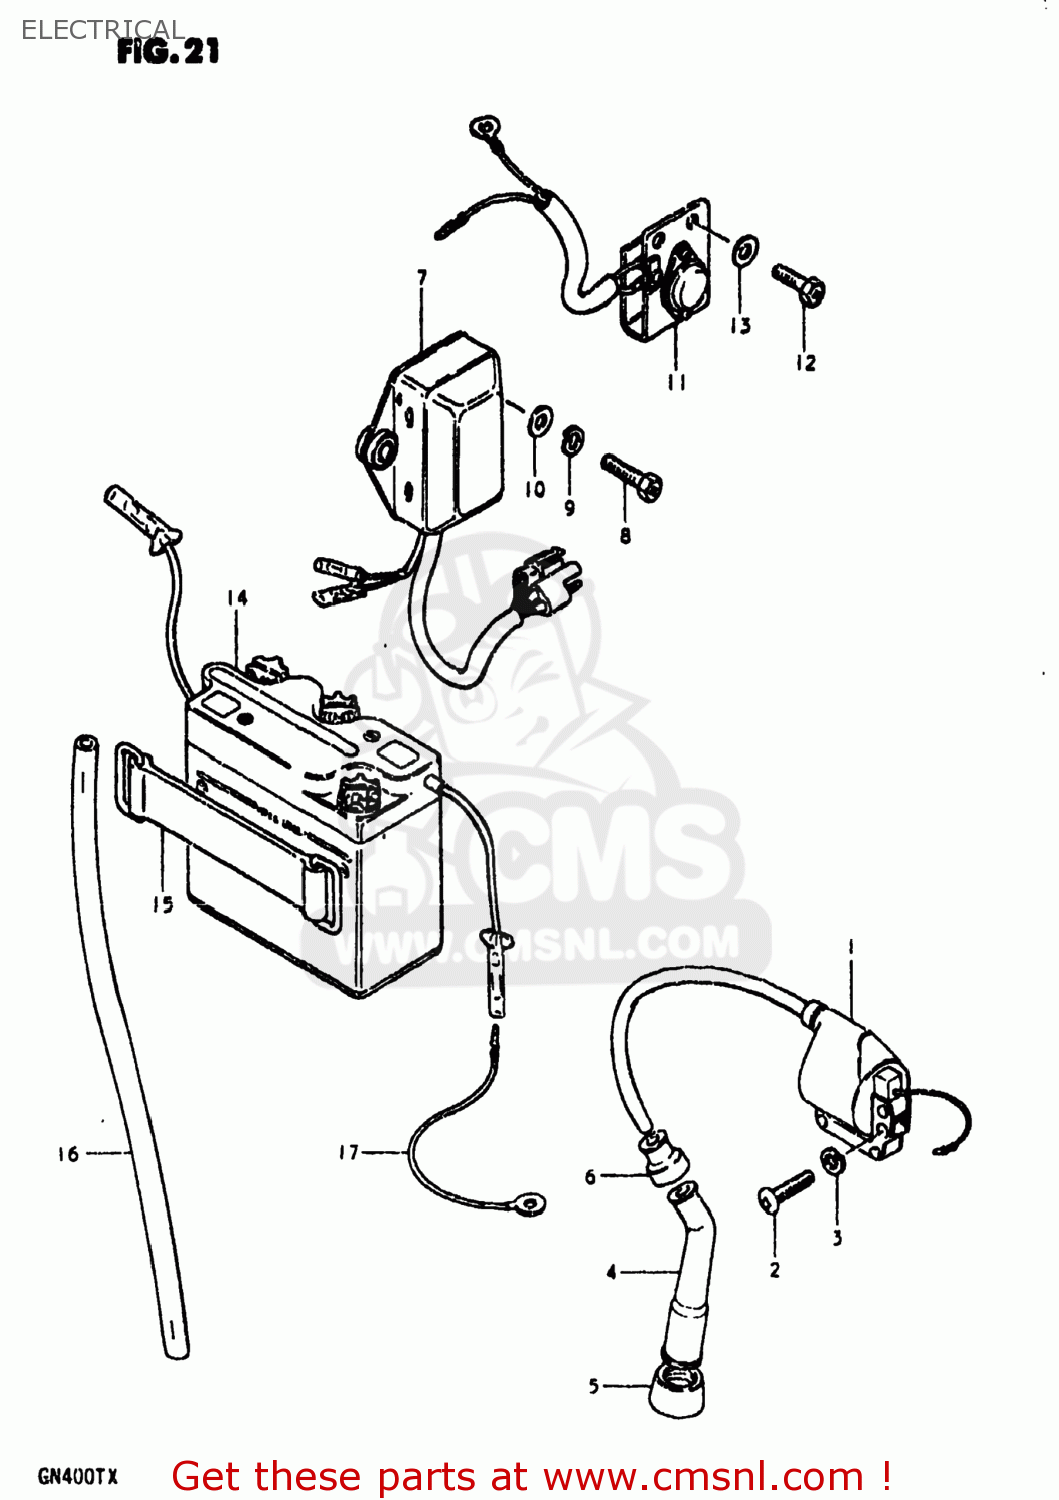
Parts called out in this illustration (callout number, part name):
1	COIL ASSEMBLY,IGNITION
2	SCREW
3	LOCK WASHER
4	CAP ASSY,SPARK PLUG
5	SEAL,SPARK PLUG
6	SEAL,SPARK PLU
7	CDI UNIT
8	BOLT(6X20)
9	LOCK WASHER
10	WASHER
11	REGULATOR ASSEMBLY
12	SCREW
13	WASHER
14	BATTERY ASSEMBLY
15	BAND
16	HOSE,BATTERY EXHAUST
17	LEAD WIRE
